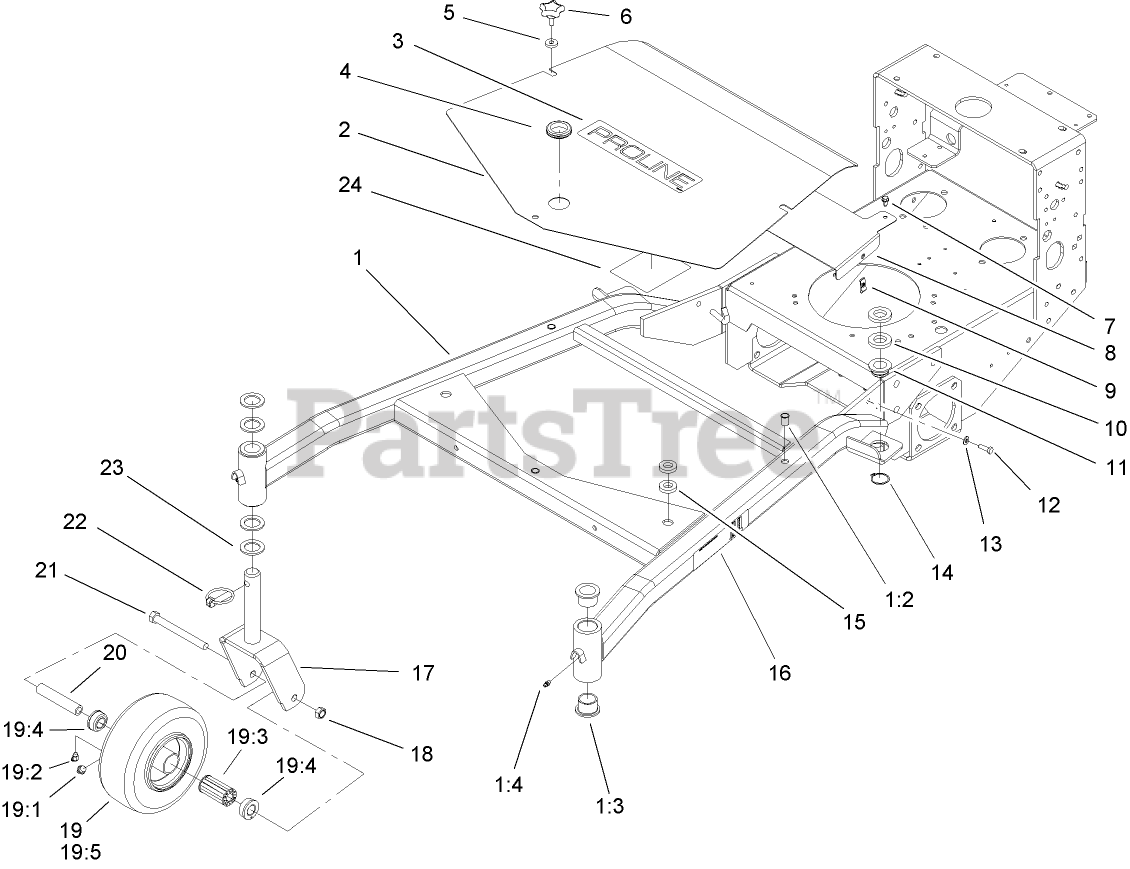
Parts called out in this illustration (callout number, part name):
1	CARRIER FRAME ASM
1:2	INSERT-NUT
1:3	BUSHING
1:4	FITTING-GREASE
2	COVER-FRAME, CARRIER
4	GROMMET-RUBBER
5	WASHER-RUBBER
7	SCREW
8	SHIELD-HEAT
9	NUT-SPEED
10	SPACER-SUPPORT, DECK
11	BUSHING-DECK
12	SCREW-HH
13	WASHER-FLAT
14	RING-RETAINING
15	SPACER
16	DECAL-HOC
17	FORK-CASTOR
18	NUT-HEX
19	CASTER WHEEL ASM
19:1	STEM-VALVE
19:2	FITTING-LUBE, 45 DEG
19:3	BEARING
19:4	BEARING-OUTSIDE
19:5	TIRE-TUBELESS
20	BUSHING-SPANNER
21	SCREW-HH
22	PIN-LYNCH
23	WASHER-THRUST
24	DECAL-SERVICE, HYDRO (TBAR)
24	DECAL-SERVICE, GEAR (TBAR)
24	DECAL-SERVICE, GEAR (PISTOL GRIP)
24	DECAL-SERVICE, HYDRO (PISTOL GRIP)
